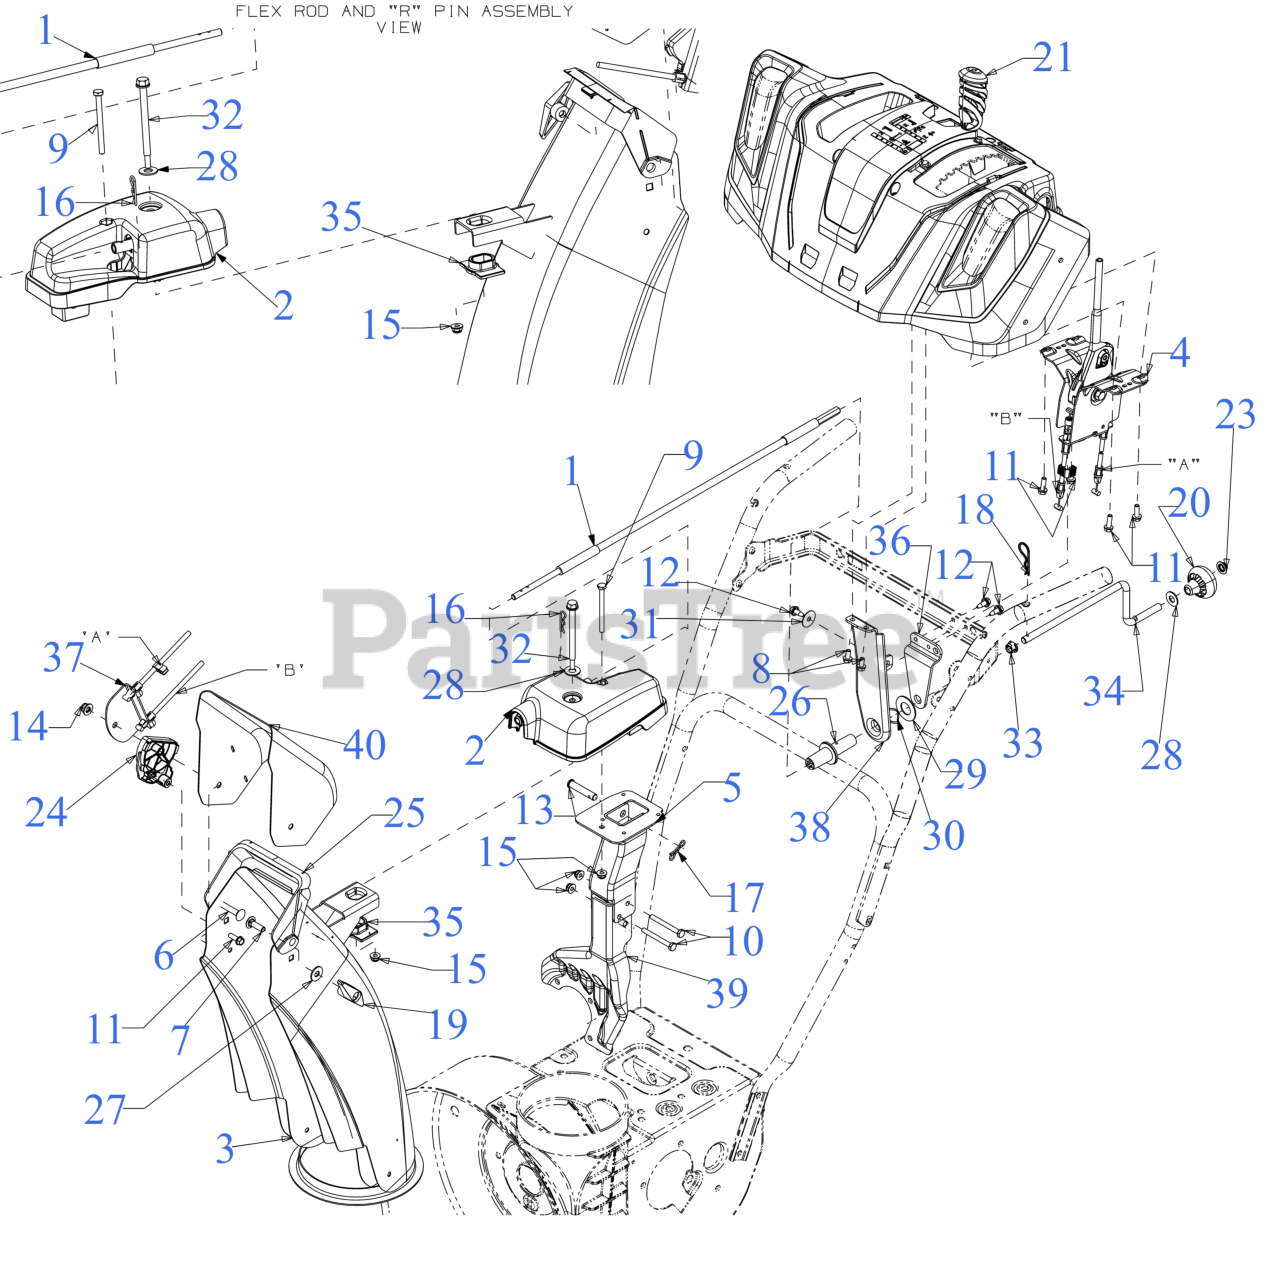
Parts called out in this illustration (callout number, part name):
1	CONTROL ASSEMBLY
2	2-WAY CHUTE ROTATE GEARBOX
3	LOWER STEEL CHUTE 6" DIA
4	2-WAY STEEL CHUTE CONTROL ASSEMBLY
5	EXTENSION CHUTE MAST
6	CARRIAGE BOLT 5/16-18 x 1.50
7	CARRIAGE BOLT 5/16-18 x 1.00
8	HEX SCREW 1/4-15 x .50
9	SCREW 1/4-20 x 3.0 GR5
10	SCREW 1/4-20 x 2.25 GR5
11	SCREW 1/4-15 x .750
12	SCREW 1/4-20X.625
13	CLEVIS PIN 3/8 x 1.87
14	FLANGE LOCK NUT 5/16-18
15	FLANGE LOCK NUT
16	INTERNAL COTTER PIN
17	BOW TIE COTTER PIN 1/4-5/16
18	INTERNAL COTTER PIN
19	WING KNOB NUT
20	SHIFT KNOB
21	PTO HANDLE GRIP .355 ID
24	CHUTE TILT GUIDE
25	UPPER CHUTE ADAPTER
26	CHUTE ROD COUPLER
27	FLAT WASHER
28	FLAT WASHER
29	FLAT WASHER
30	WAVE WASHER .785X1.00X.012
31	FLAT WASHER
32	SHOULDER SCREW
33	BUSHING .380 ID
34	CHUTE CRANK (POWDER BLACK)
35	HELICAL GEAR CHUTE ADAPTER
36	ROD SUPPORT BRACKET
40	UPPER STEEL CHUTE (REMOTE TILT)
